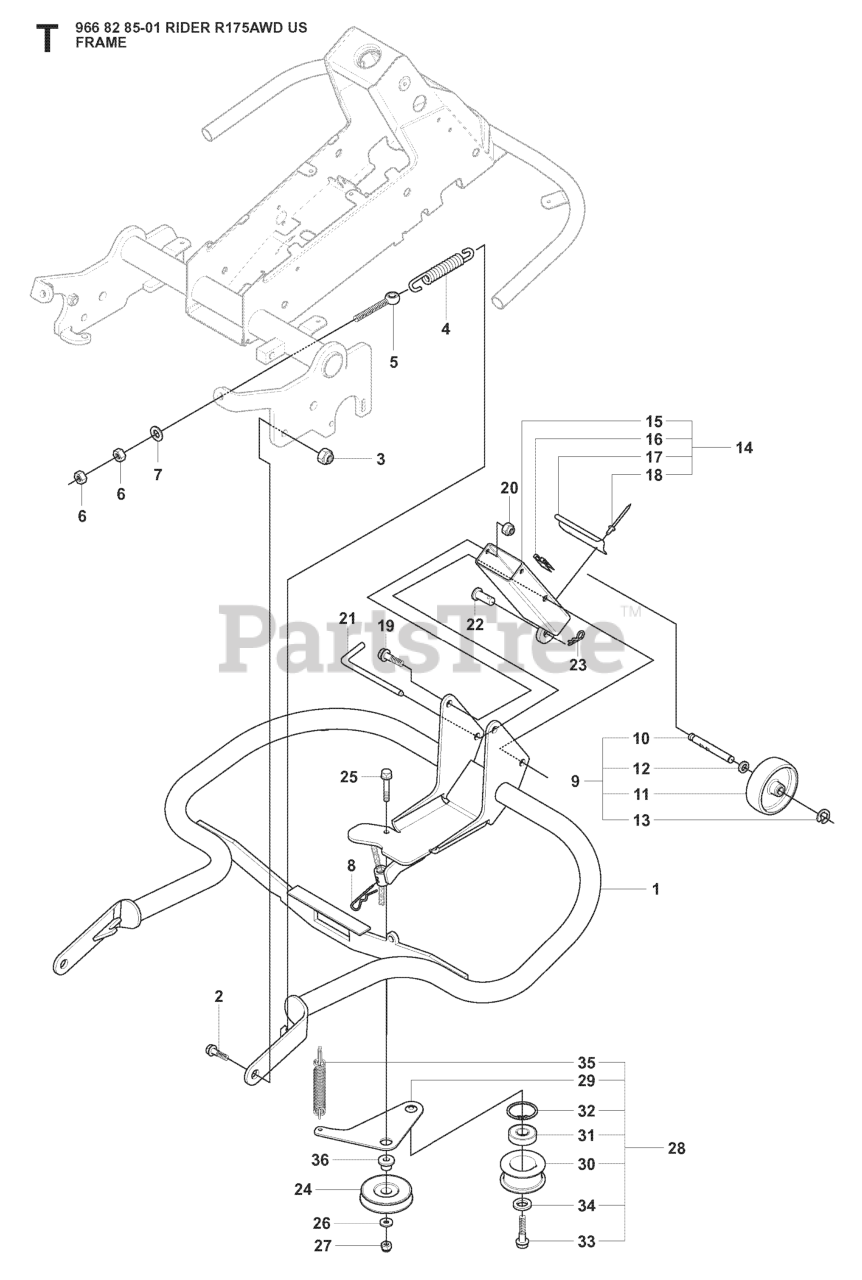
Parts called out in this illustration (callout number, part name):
1	DECK FRAME
6	NUT
7	WASHER
9	WHEEL ASSY
13	RETAINING RING
20	LOCKNUT M8
27	LOCKNUT M8
28	BELT TENSIONER ASSY
30	%PULLEY
31	BALL BEARING 6004-2RS1
32	RETAINING RING
35	SPRING
